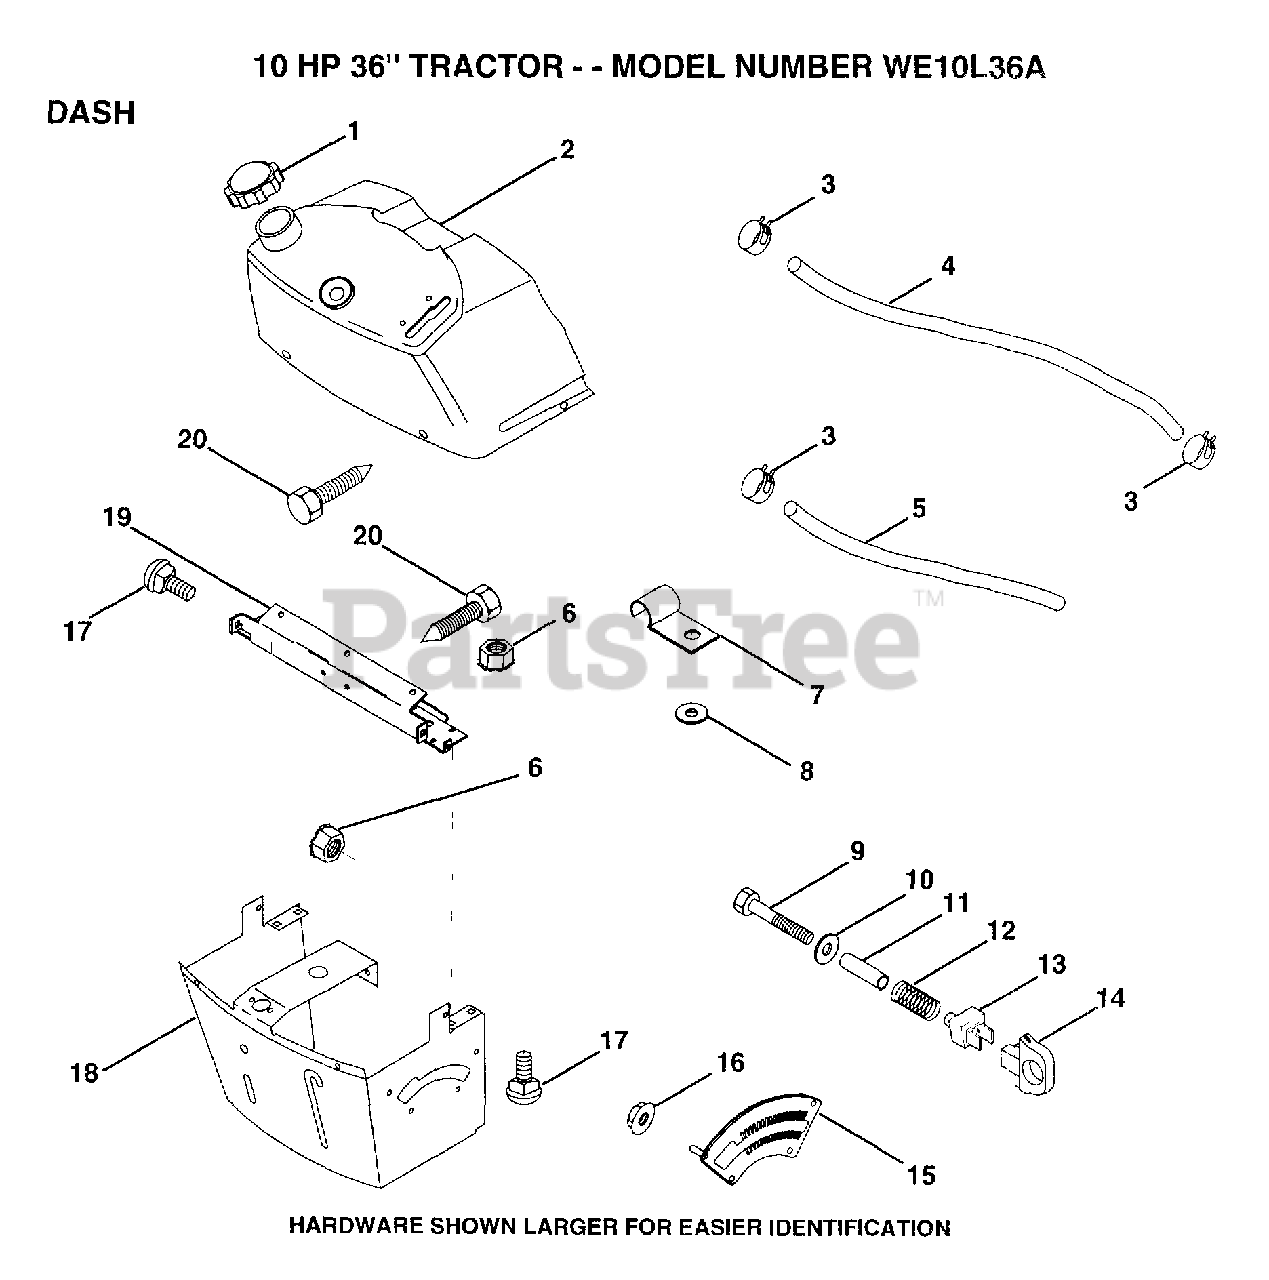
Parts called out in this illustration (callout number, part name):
1	CAP.FUEL.N/VENT
2	TANK.ASM.DASH.LR
3	HOSE CLAMP
5	FUEL LINE T
6	NUT
7	CLIP T
8	WASHER PM
9	BOLT
11	SPACER SPLIT
12	SPRING M
13	"KNOB,HGT RETAINER"
14	KNOB
15	ADJUSTER QUAD
16	NUT
17	BOLT
18	SUPT ASSY DASH
19	CROSS BRACE
20	SCREW.1/4-20X1/2
